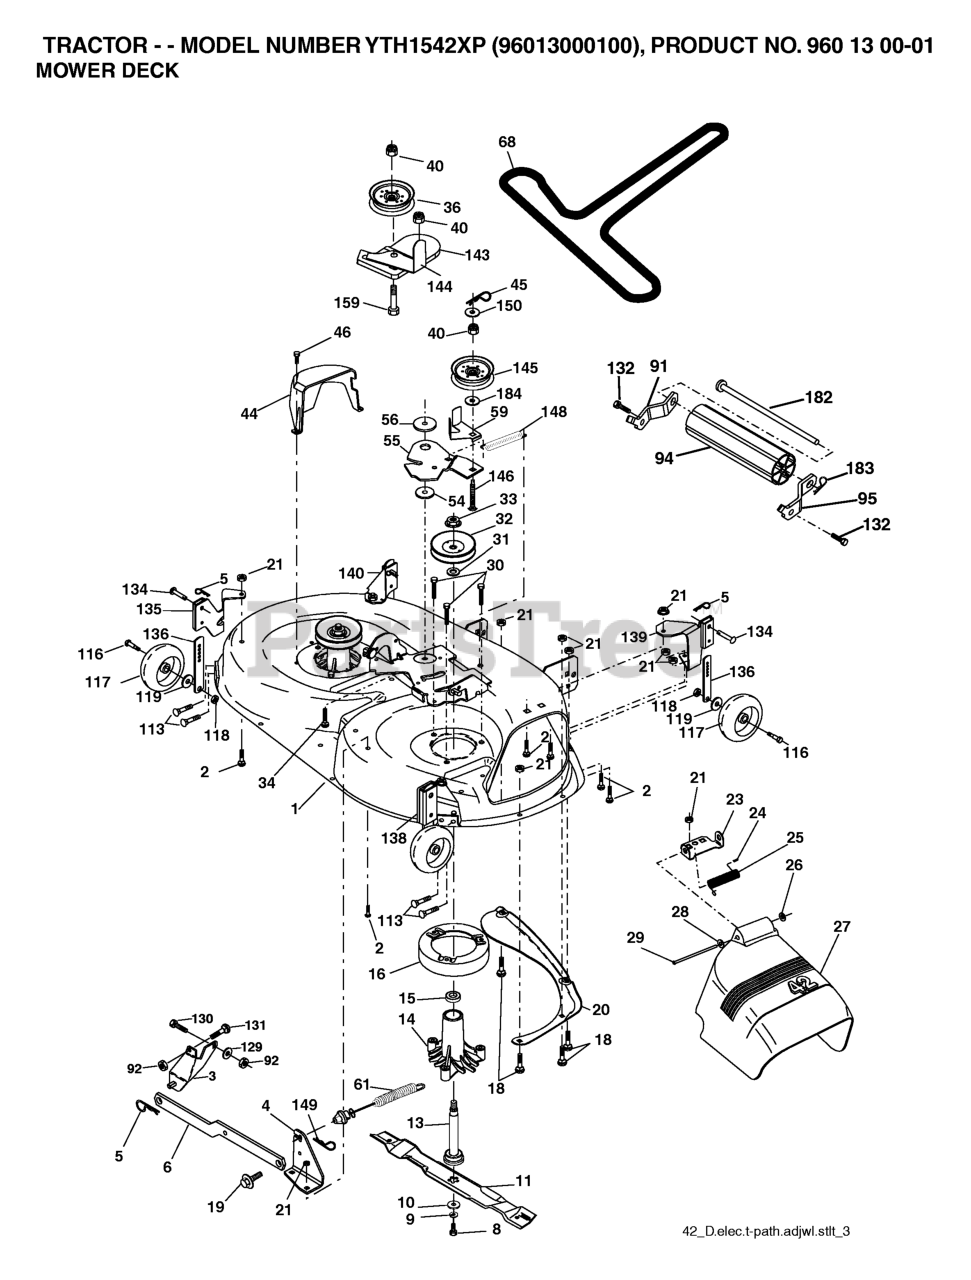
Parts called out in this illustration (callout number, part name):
1	MOWER DECK SHELL 42"
2	RP BOLT 5/16-18 X3/4 ZN/YEL GR
3	BRKT ASM SWAY BAR
4	BRACKET SWAY BAR 42" DECK
5	RETAINER-SPRNG RB
6	BAR SWAY DECK
8	BLADE BOLT
9	LOCKWASHER
10	WASHER.BLADE
11	42" HI-LIFT BLADE
13	SHAFT ASM VENT
14	HOUSING.MANDREL.VENTED (MACHD)
16	STRIPPER.MANDREL.ROUND.BLACK
18	BOLT
19	BOLT SHD 5/16-18
20	BAFFLE.VORTEX
21	LOCKNUT
23	BRKT, DEFL. MOWER
24	CAP-SLEEVE LT
25	SPRING TORSION
26	NUT PUSH M
27	SHIELD DEFLECTOR
28	Washer 11/32 x 5/8 x 16 Ga SD
29	ROD.HINGE
30	SCREW, WASHER HEAD
31	WASHER.SPACER.MANDREL
32	PULLEY MANDREL
33	NUT, FLG TOPLOCK 9/16"
34	BOLT.3/8-16X1.50
36	PULLEY.IDLER.FLAT
40	NUT LOCK FLG 3/8-16 UNC
44	GUARD MANDREL LH BLACK
45	RETAINER M
46	SCREW.1/4-20X5/8
55	ARM IDLER 42" MOWER LT/YT
56	SPACER RETAINER
59	GUARD, BELT
61	SPRING EXT ELEC CLUTCH
68	V-BELT PRIMARY 42"
91	BRACKET ASM NOSEROLLER LH
92	NUT
94	NOSE ROLLER
95	BRACKET ASM NOSEROLLER RH
113	BOLT.5/16HEX.WHS.HD
116	BOLT.SHOULDER.3/8-16X3-5/8.
117	RP WHEEL. GUAGE RALLY
118	LOCKNUT
119	WASHER.5/16.FLAT.STE.STD.
129	WASHER
131	BOLT D
132	SCREW, 3/8-16X3/4
134	RIVET.PIN.HEAD.YELLOW.
135	BRACKET ASM, WHEEL
136	BAR.ADJUST.WHEEL.ANTI.SCALP.BL
138	BRACKET.ASM.WHL.GA.R.RH.42".GR
139	BRACKET ASM, WHEEL
140	BRACKET ASM, WHEEL
143	BRACKET, ARM IDLER
144	KEEPER BELT 42" CLUTCH
145	PULLEY.IDLER.FLAT.PLATED
146	BOLT CARRIAGE IDLER
148	IDLER RETURN SPRING
149	SPRING.RETAINER.YELLOW.ZINC
182	ROD ROLLER NOSE STANDARD
183	SPRING RETAINER
184	WASHER
